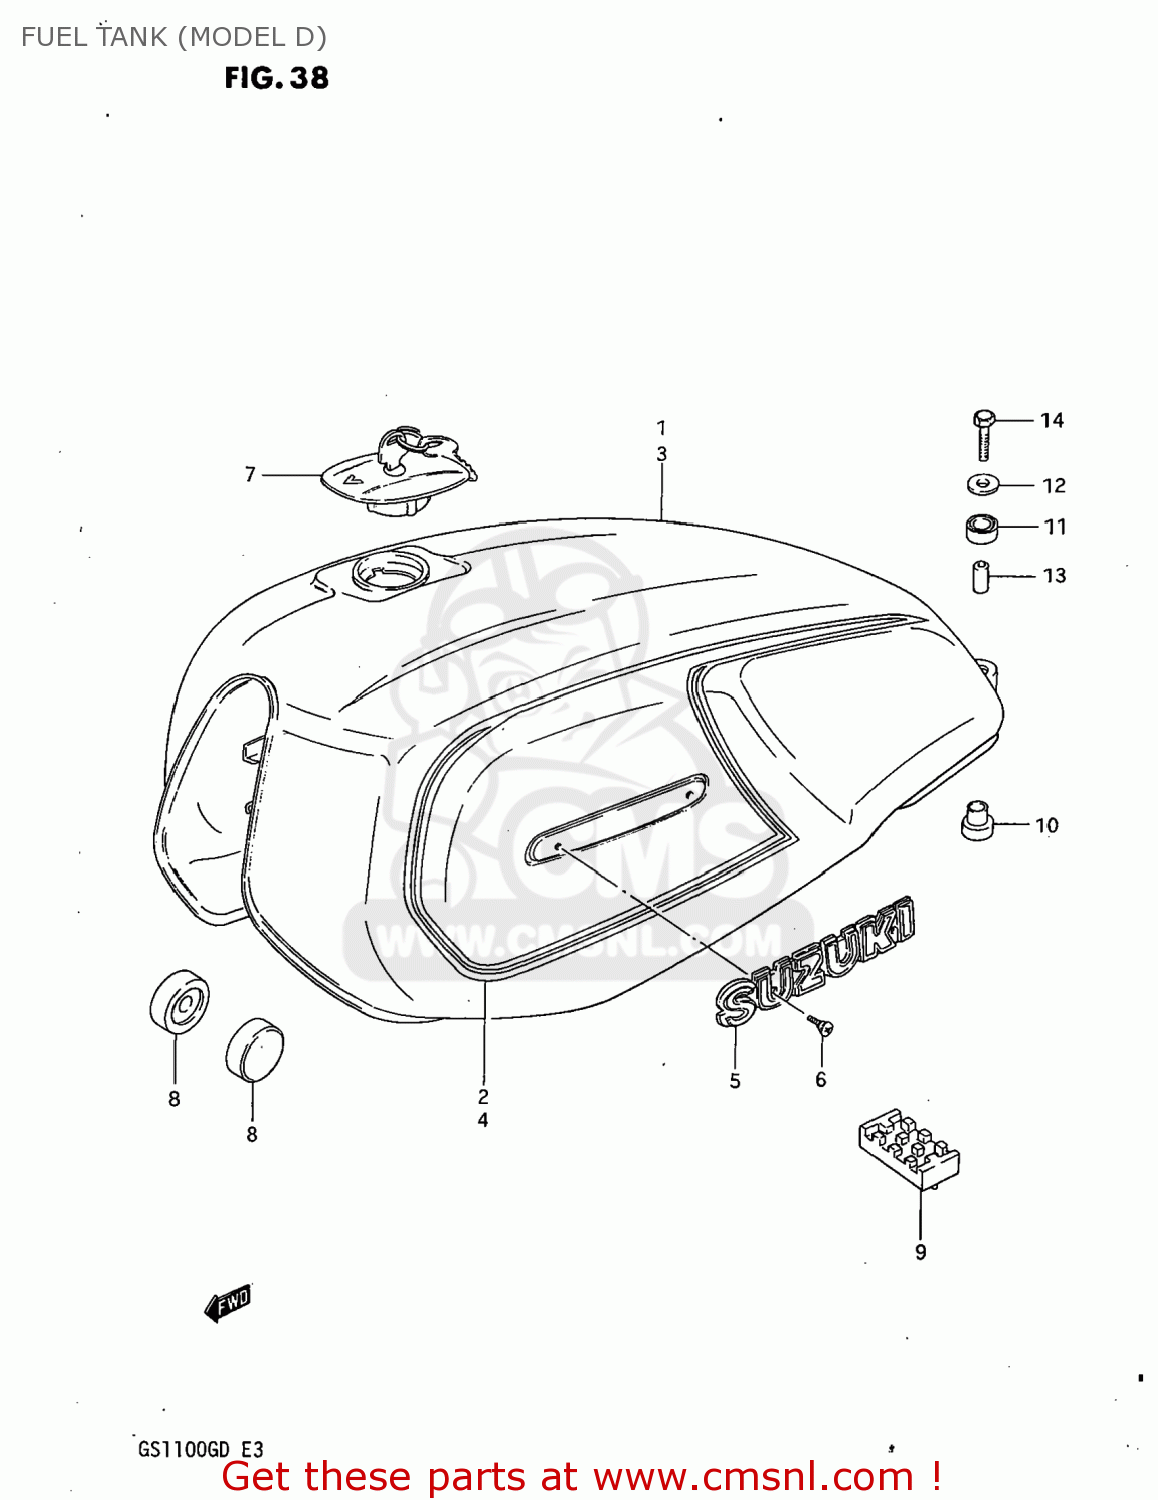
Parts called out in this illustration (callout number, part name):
1	TANK ASSEMBLY,FUEL
2	TAPE SET,FUEL TANK
3	TANK ASSEMBLY,FUEL
4	TAPE SET,FUEL TANK
5	EMBLEM
6	SCREW 3X6
7	CAP SET,FUEL TANK
8	CUSHION
9	CUSHION,FUEL TANK
10	CUSHION
11	CUSHION
12	WASHER (6.5X24X1.6)
13	SPACER (6.4X9X21.5)
14	BOLT
